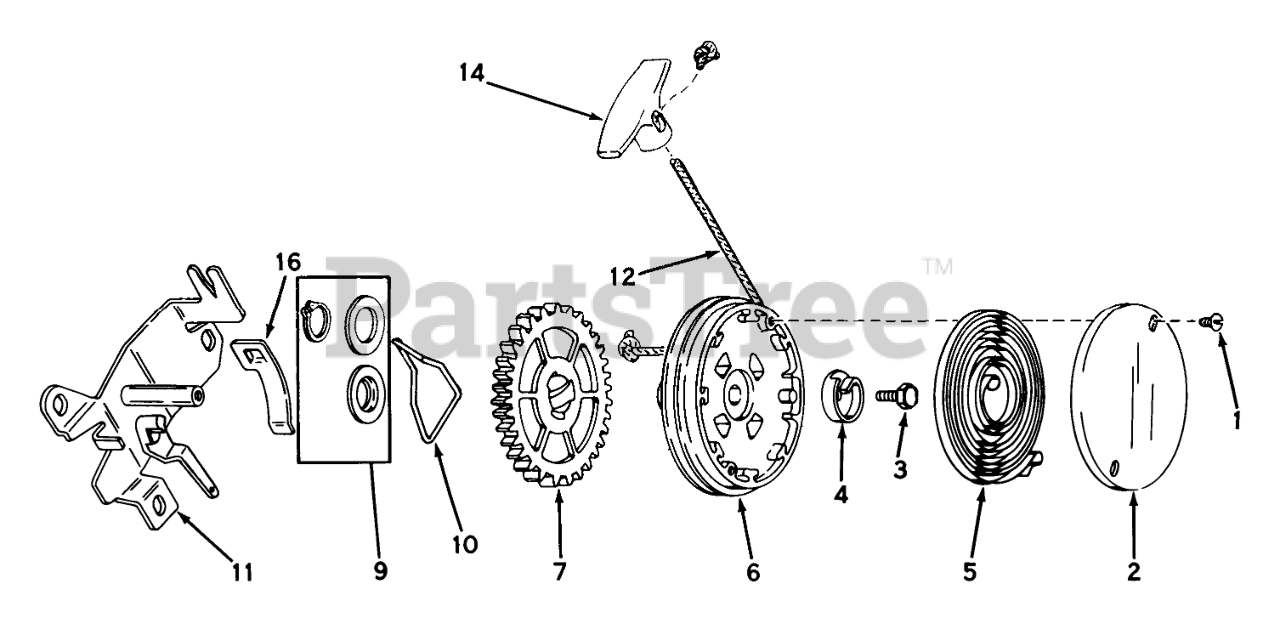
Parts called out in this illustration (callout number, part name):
2	Cover, Spring
3	Screw, Hex Washer Head
4	Hub Spring
5	Spring, Rewind
6	Pulley Assy. (Incl. No. 9)
11	Bracket Assy., Mounting
12	Rope-Starter
14	Handle-Starter
16	Clip Rope
